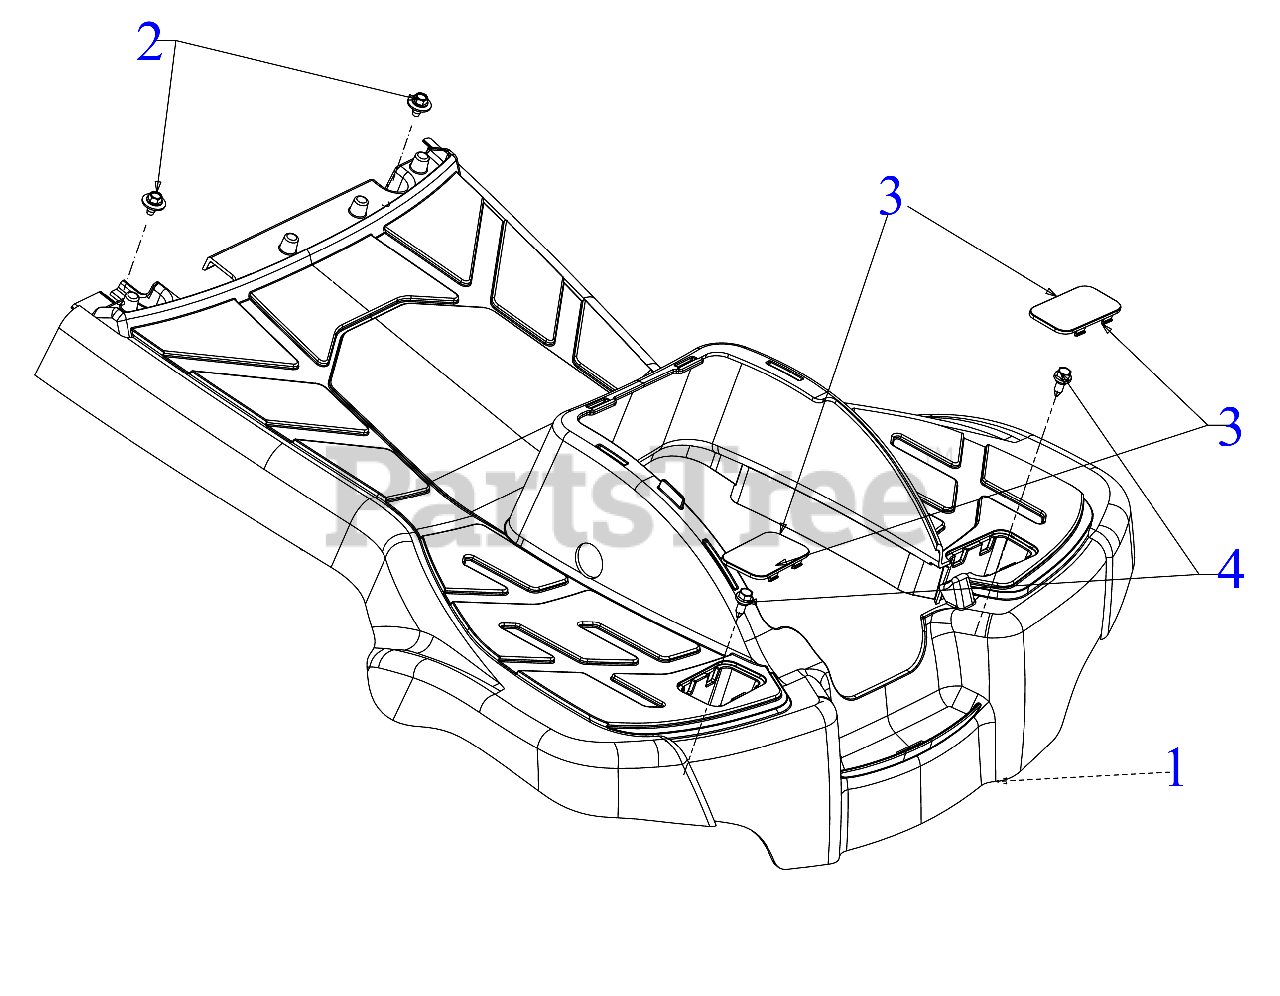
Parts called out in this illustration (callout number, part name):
1	RUNNING BOARD
2	SCREW 1/4-20 x .50
3	RUNNING BOARD PLUG
4	SHOULDER SCREW
